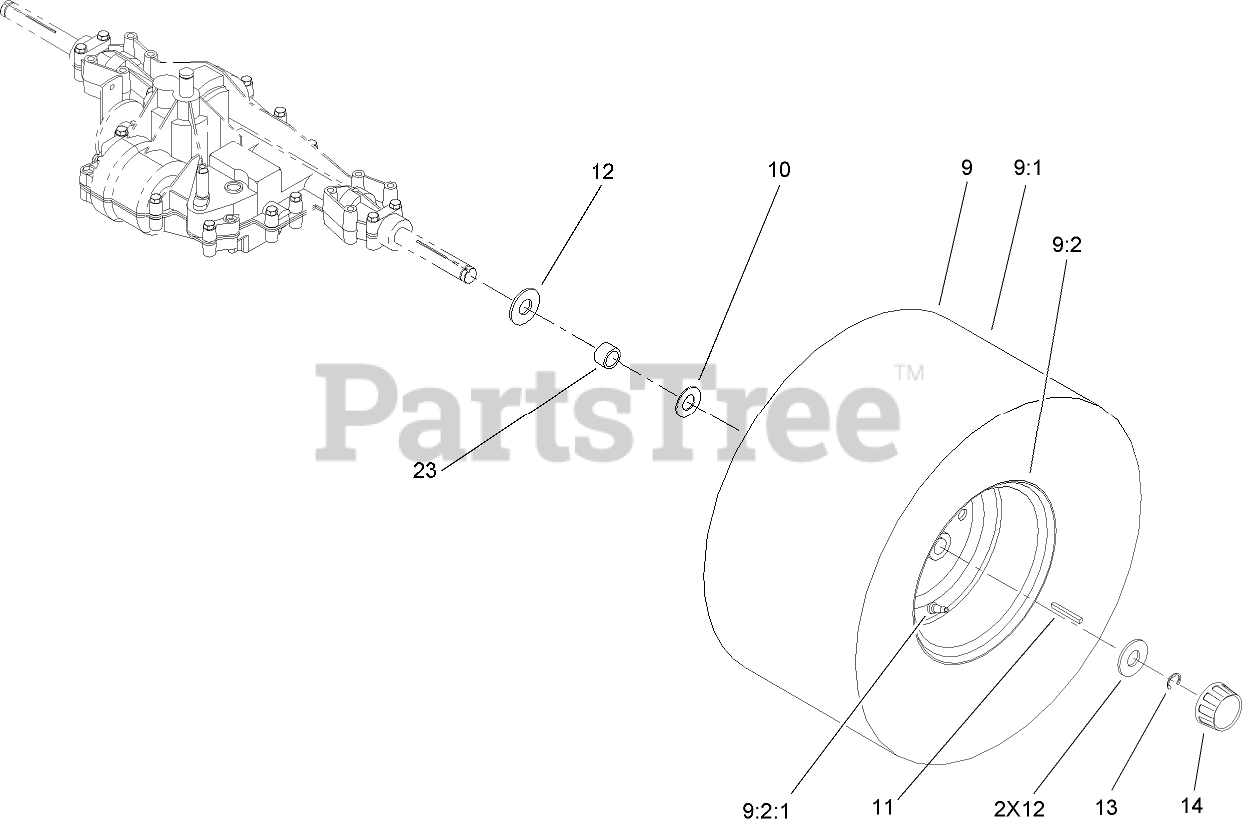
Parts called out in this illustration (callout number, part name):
9	REAR WHEEL & TIRE ASM
9:1	TIRE
9:2:1	STEM-VALVE
10	WASHER-THRUST
11	KEY-SQUARE
12	WASHER-PLAIN
13	E-RING
14	CAP-HUB
23	SPACER-WHEEL
